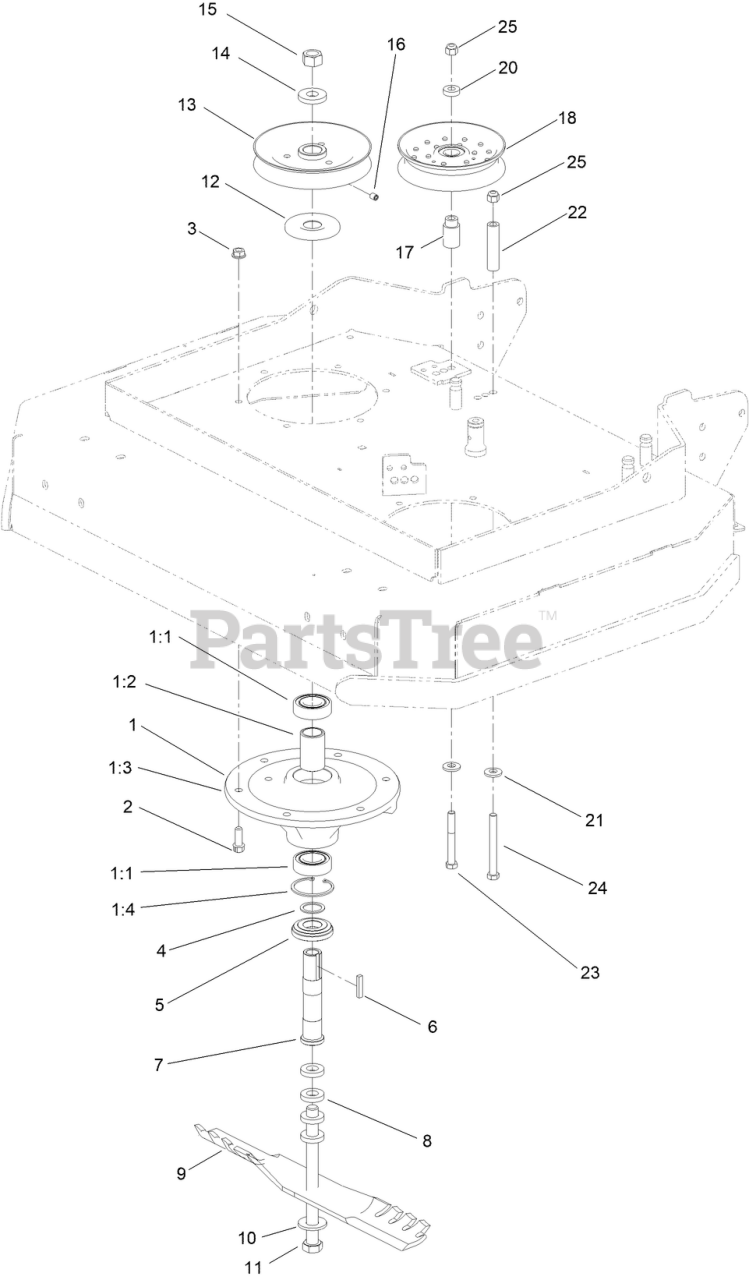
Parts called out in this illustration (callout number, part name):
1	SPINDLE HOUSING ASM
1:1	BEARING-BALL, 1 INCH
1:2	SPACER-BEARING
1:3	HOUSING-SPINDLE
1:4	RING-SNAP
2	SCREW-TAPTITE
3	NUT-HHF, WHIZ
4	WASHER-SPACER
5	SPACER-GUARD, BOTTOM
7	TUBE-SPINDLE, SHORT
8	SPACER
9	BLADE-ATOMIC
10	WASHER-SPRING
11	SCREW-CAP, HH
12	GUARD-BEARING, TOP
13	SHEAVE
14	WASHER-RETAINER, SHEAVE
15	NUT-HEX
16	SCREW-SET
17	BUSHING-IDLER
18	PULLEY-IDLER,FLAT
20	SPACER
21	WASHER-BELLEVILLE
22	SPACER
23	SCREW-HH
24	SCREW-HH
25	NUT-LOCK, NI
